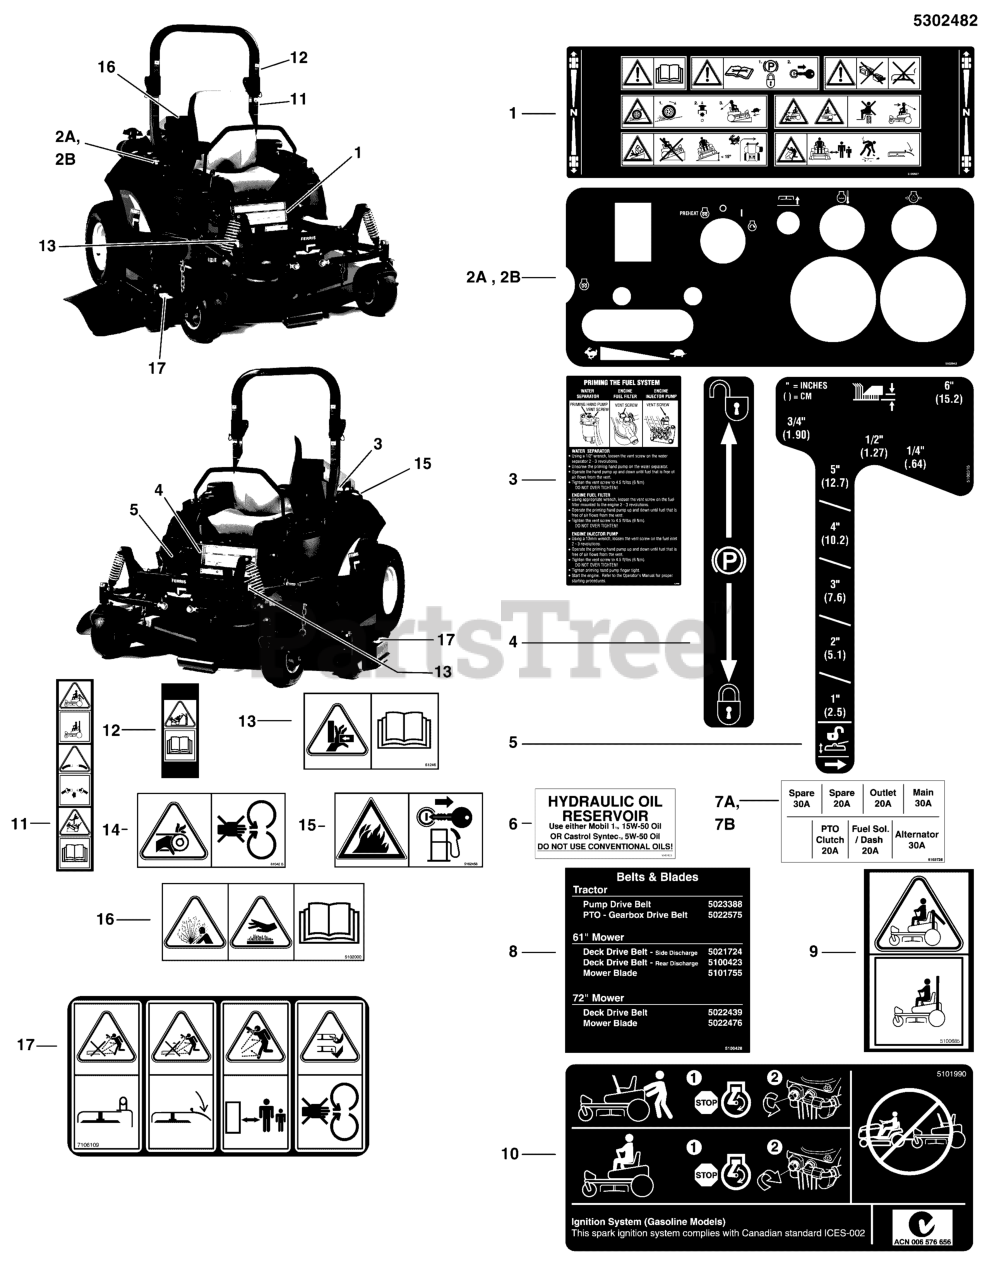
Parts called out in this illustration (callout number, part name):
1	DECAL, MAIN SAFETY, ANSI CE
2A	DECAL, CONTROL PANEL, IS5100
2B	DECAL, CONTROL PANEL, IS5000Z
3	DECAL, PRIMING INSTRUCTIONS
4	DECAL, PARKING BRAKE SYMBOLS
5	DECAL, HEIGHT OF CUT, IS5000Z
6	DECAL-OIL RESERVOIR
7A	DECAL, FUSE LOCATION
7B	DECAL, FUSE LOCATION, IS5100Z, MECH-LIFT
8	DECAL, BELT & BLADE, IS5100Z
9	DECAL, WARNING, ROLL BAR, CE
10	DECAL, CZT HYRDO RELEASE
11	DECAL, SAFETY, CE ROPS
12	DECAL, SAFETY, CE ROPS, OBS
13	DECAL, PINCH POINT, CE
14	DECAL, CE DANGER
15	DECAL, FIRE ANSI EXPORT
16	DECAL, WARNING, HOT
17	DECAL, DISCHARGE SAFETY, EXPORT
